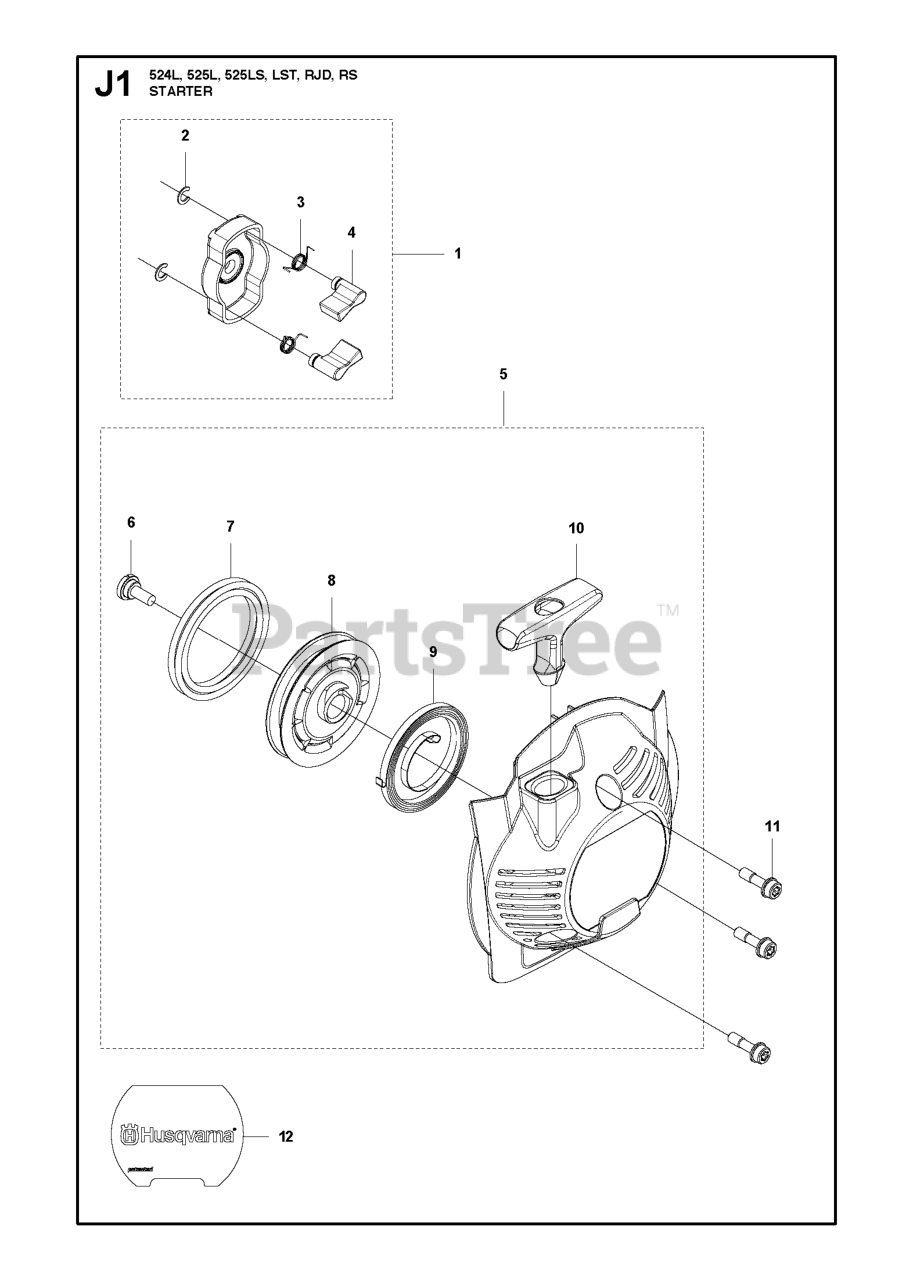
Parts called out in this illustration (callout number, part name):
6	SCREW
8	STARTER PULLEY
10	STARTER HANDLE
11	BOLT
12	DECAL STARTER
